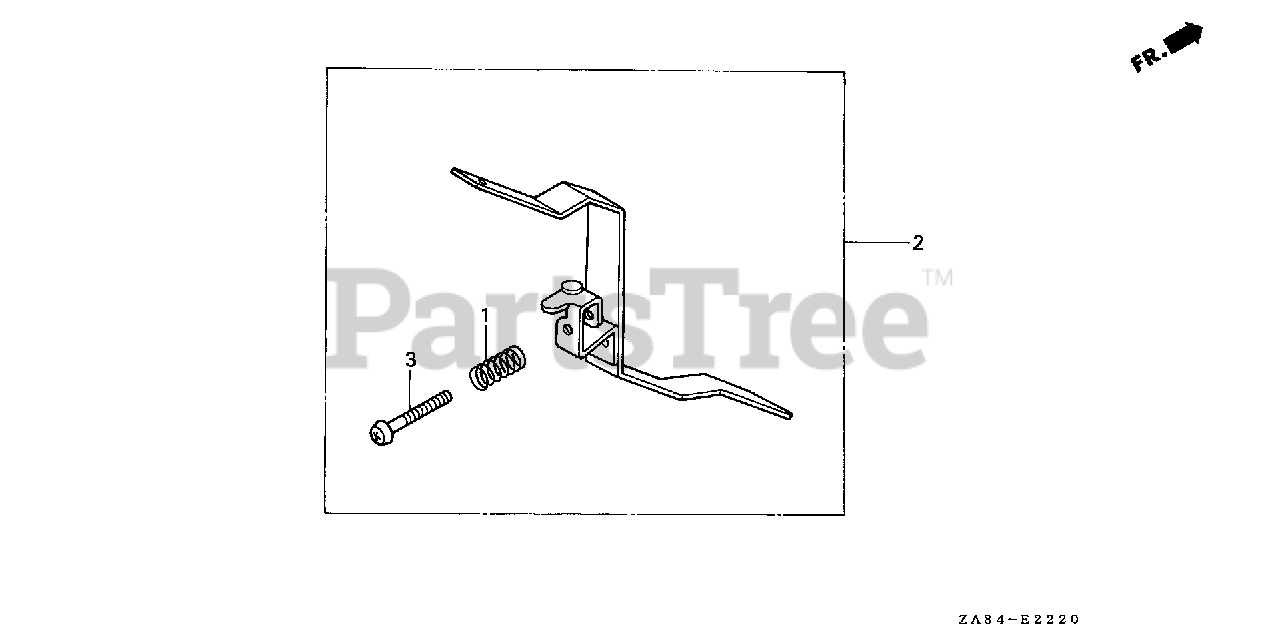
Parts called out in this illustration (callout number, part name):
1	SPRING, CONTROL ADJUSTING
2	ADJUSTER, FREQUENCY
3	SCREW, PAN (4X18)
